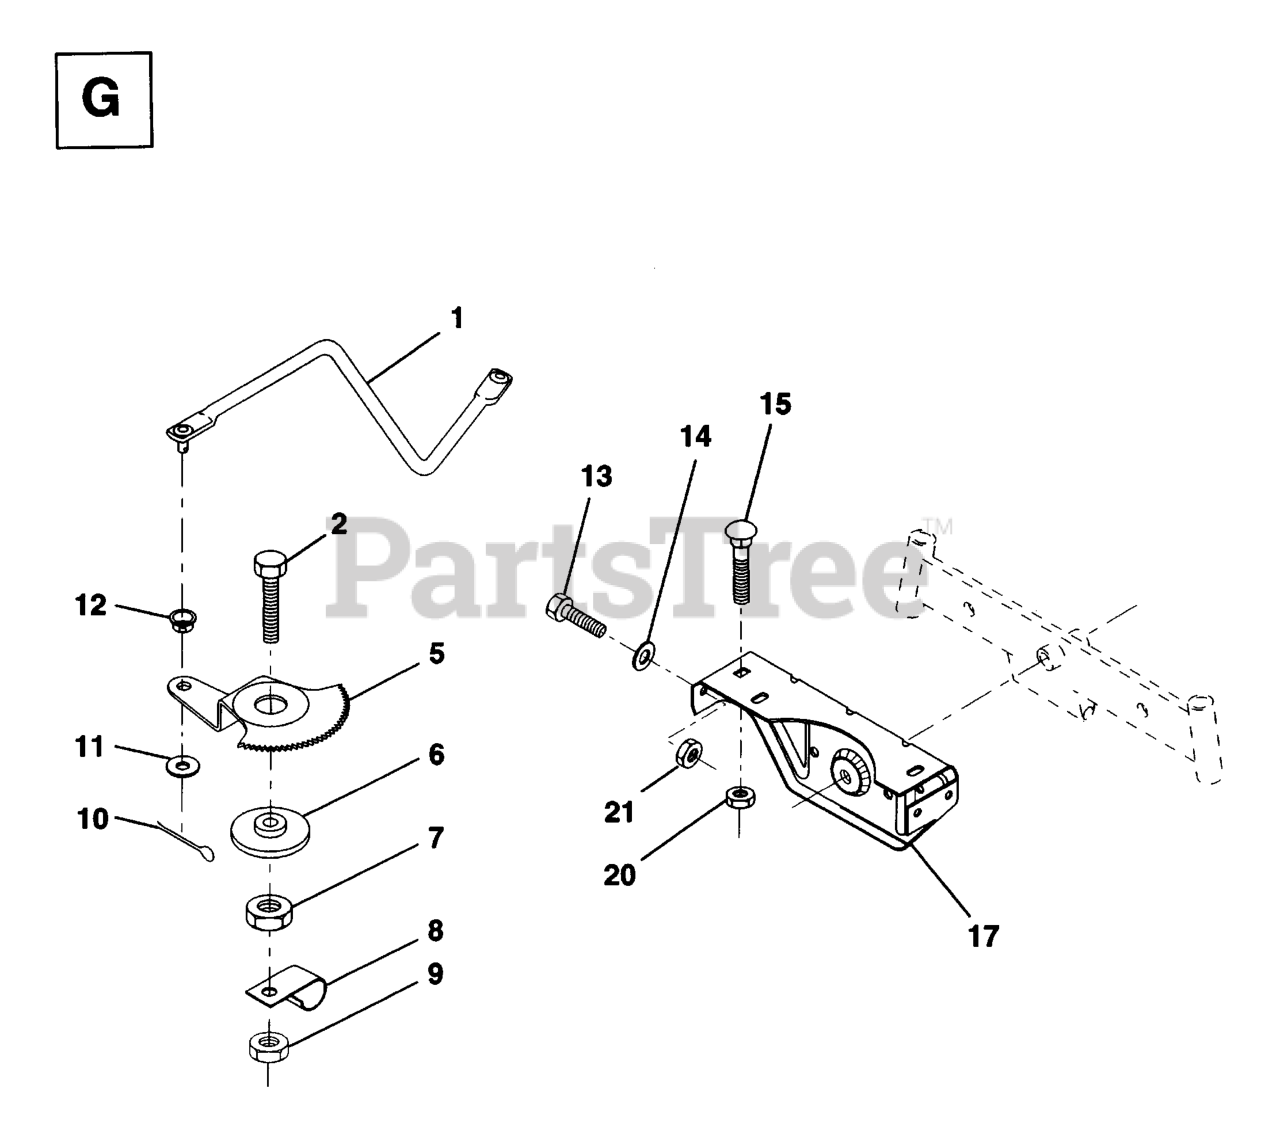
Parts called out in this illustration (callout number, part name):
5	GEAR SECTOR
7	NUT
8	CLIP INSULATOR
9	NUT LTV
10	COTTER PIN
11	WASHER
12	BUSHING.DRAGLINK (2 2)
13	BOLT RB
14	WASHER
17	SUPPORT/AXLE FRONT
20	NUT
21	LOCKNUT
